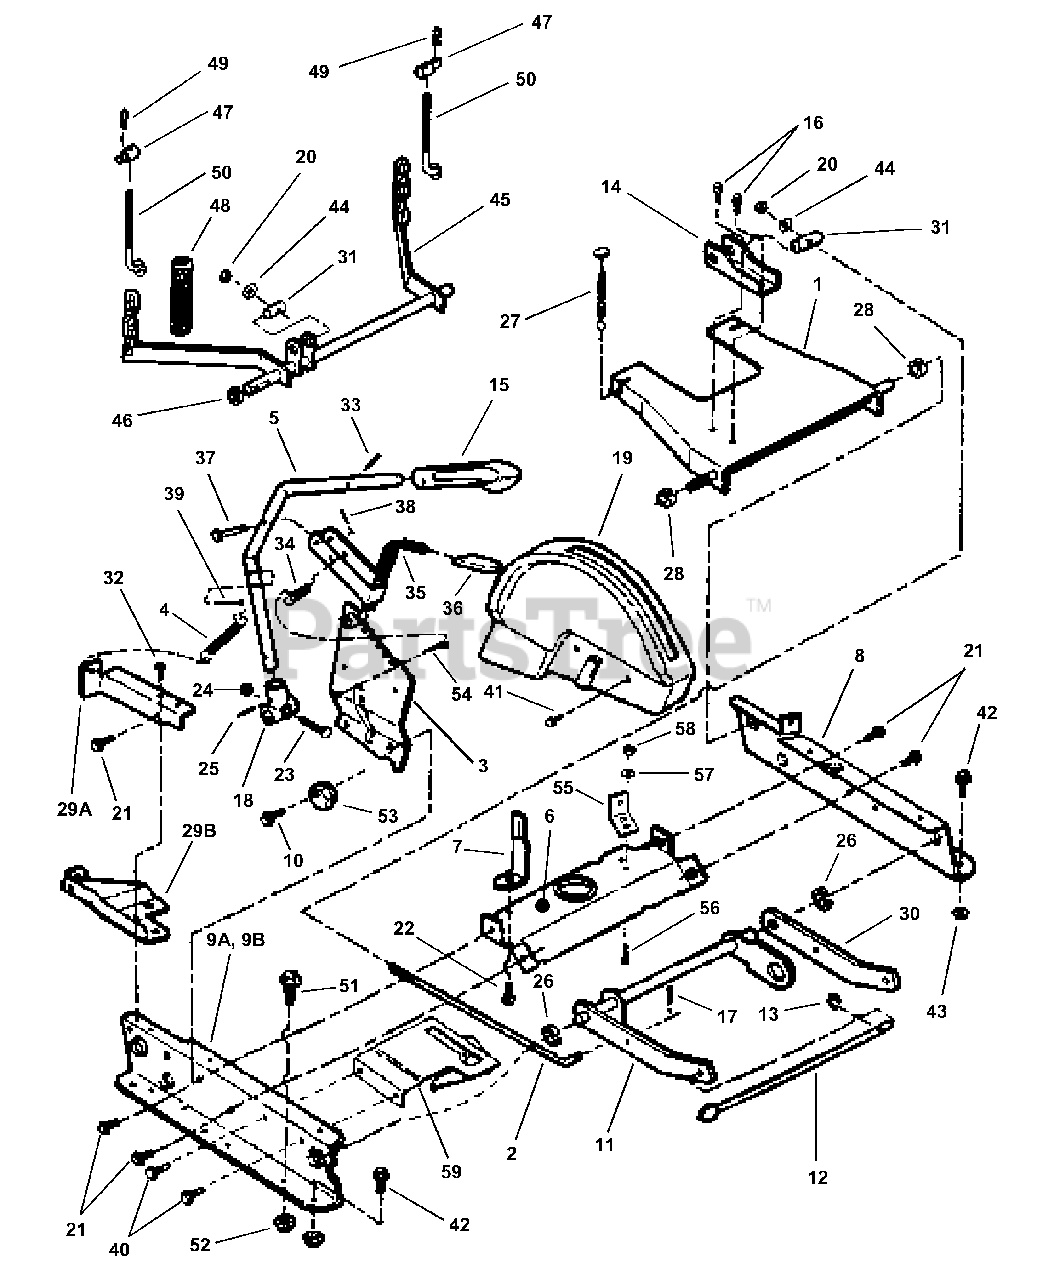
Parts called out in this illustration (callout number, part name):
1	ARM, Rear Lift (25" Deck Only)
2	ROD, Leveling (15.3" L, 3/4-24 thread)
3	WELDMENT, Quadrant,5 Position
4	SPRING, Extension
5	LEVER, Lift
6	BRACE, Top
7	GUIDE, Belt
8	RAIL, Left Hand
9A	RAIL, R.H. (25" Deck)
9B	RAIL, R.H. (28", 30" & 33" Decks)
10	SCREW, 3/8-16 x 1" Hex Washer Self-Tap
11	ARM, Front Lift, Adjustable (28", 30 & 33" Decks)
12	ROD, Support (Front Lift Arm to Front End)
13	SNAP RING, 7/16" External
14	ARM, Leveling (25" Deck)
15	GRIP, Height Adjustment Lever
16	SCREW, 5/16-18 x 5/8" Truss Head Self-Tap (Torx)
17	PIN, 1/8 x 3/4" Cotter
18	HUB, Deck Lift
19	COVER, Height of Cut
20	NUT, 3/8-24 Hex Nyloc
21	SCREW, 3/8-16 x Hex Washer Self-Tap
22	SCREW, 5/16-18 x 5/8" Hex Washer Self-Tap
23	BOLT, 5/16-24 x 1-5/8" Tapered Axle
24	NUT, 5/16-24 Hex Flange Lock
25	PIN, 3/16 x 1" Roll
26	RING, Red
27	CABLE, Rear Deck (25" Deck)
28	RING, White (25" Deck)
29A	BRACKET, Deck Lift (25" Deck Only!)
29B	BRACKET, Lift Assist (28", 30" & 33" Decks)
30	ARM, Front Lift-Left (28, 30" & 33" Decks)
31	PIVOT, Leveling
32	SCREW, 1/4-20 x 3/4" Hex Washer Self-Tap
33	PIN, 3/16 x 3/4" Roll
34	SPRING, Latch (Black)
35	WELDMENT, Latch
36	GRIP, Lift Latch
37	PIN, 1/4 x 1-1/4" Clevis
38	PIN, 1/16 x 3/4" Cotter
39	PIN, 3/16 x 1-1/2" Cotter
40	SCREW, 5/16-18 x 1/2" Hex Washer Self-Tap
41	SCREW, 1/4-20 x 5/8" Hex Washer Self-Tap
42	BOLT, 5/16-18 x 5/8" Hex Flange Lock
43	NUT, 5/16-18 Hex Flange Lock
44	WASHER, 3/8" Flat
45	WELDMENT, Rear Lift Arm (28", 30" & 33" Decks)
46	RING, Blue
47	SWIVEL
48	COVER, Chain
49	HAIRPIN, 3/32 x 1-1/2"
50	ADJUSTER, Chain
51	BOLT, 1/4-20 x 1/2" Hex Flange Lock
52	NUT, 1/4-20 Hex Flange Lock
53	ECCENTRIC, Height-of-Cut
54	COTTER-PIN, 3/16 x 3/4"
55	ANCHOR
56	SCREW, 5/16-24 x 3/4" Hex Head Cap, Grade 5
57	WASHER, 5/16 Internal Tooth Lock
58	NUT, 5/16-24 Hex
59	ASSEMBLY, Clutch Plate
